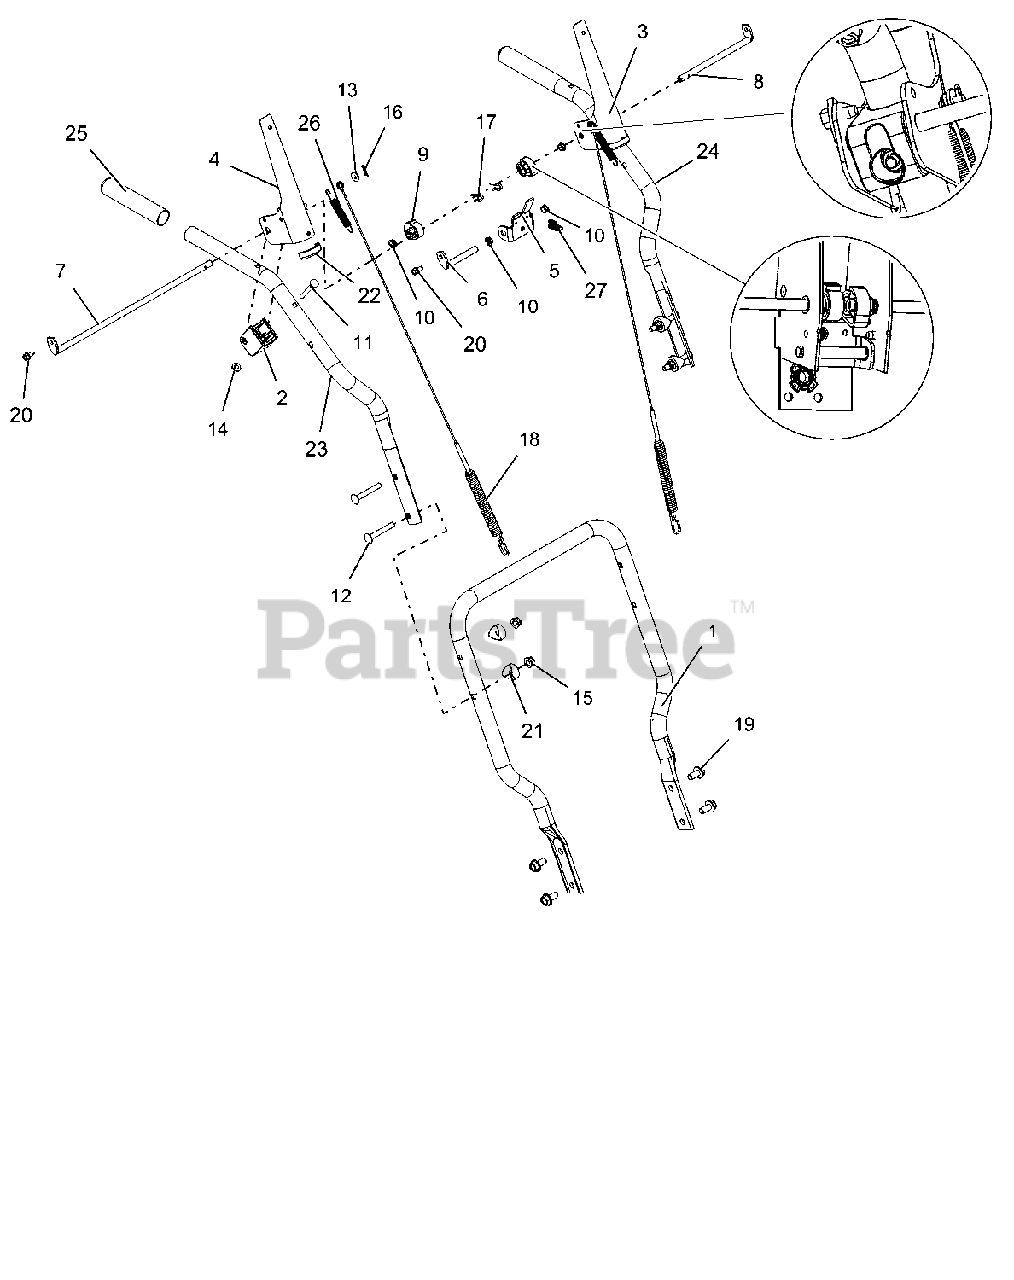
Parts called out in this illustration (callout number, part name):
1	HANDLEBAR, LOWER (COMPACT)
2	BLOCK, CLUTCH PADDLE
3	LEVER, CLUTCH-LH
4	LEVER, CLUTCH-RH
5	BRACKET, INTERLOCK ARM
6	ROD, PIVOT - INTERLOCK
7	ROD, PADDLE MOUNT - LONG
8	ROD, PADDLE MOUNT - SHORT
9	CAM, INTERLOCK
10	BUSHING, POLYLINER-.38 SNAPIN
11	BLT-RDHDXLSQNK .25-20X2.0 G5YZ
12	@BLT-RDHDSQNK .31-18X2.25 G5YZ
13	@WSHR-FL-STL.281X.62X.065 YWZC
14	@NUT-LK-TOP-FLG .25-20 YWZC
15	@NUT-LK-NYL-FLG .31-18 YWZC
16	PIN-HAIR INT .06X.18X.77
17	PIN, SPRING CLIP
18	CABLE, AUGER & UPPER TRACTION
19	BLT-SERHFWH .38-16X.75 YWZC
20	SCR-TAP .25-20X.50 HWH TR YWZ
21	SPACER, HANDLEBAR
22	EDGING, CLUTCH PADDLE - 2.00"
23	HANDLEBAR, UPPER - RH
24	HANDLEBAR, UPPER - LH
25	GRIP,HANDLE-GRAY
26	SPRING, EXTENSION
27	SPRING-EXT .047X.438X1.45
